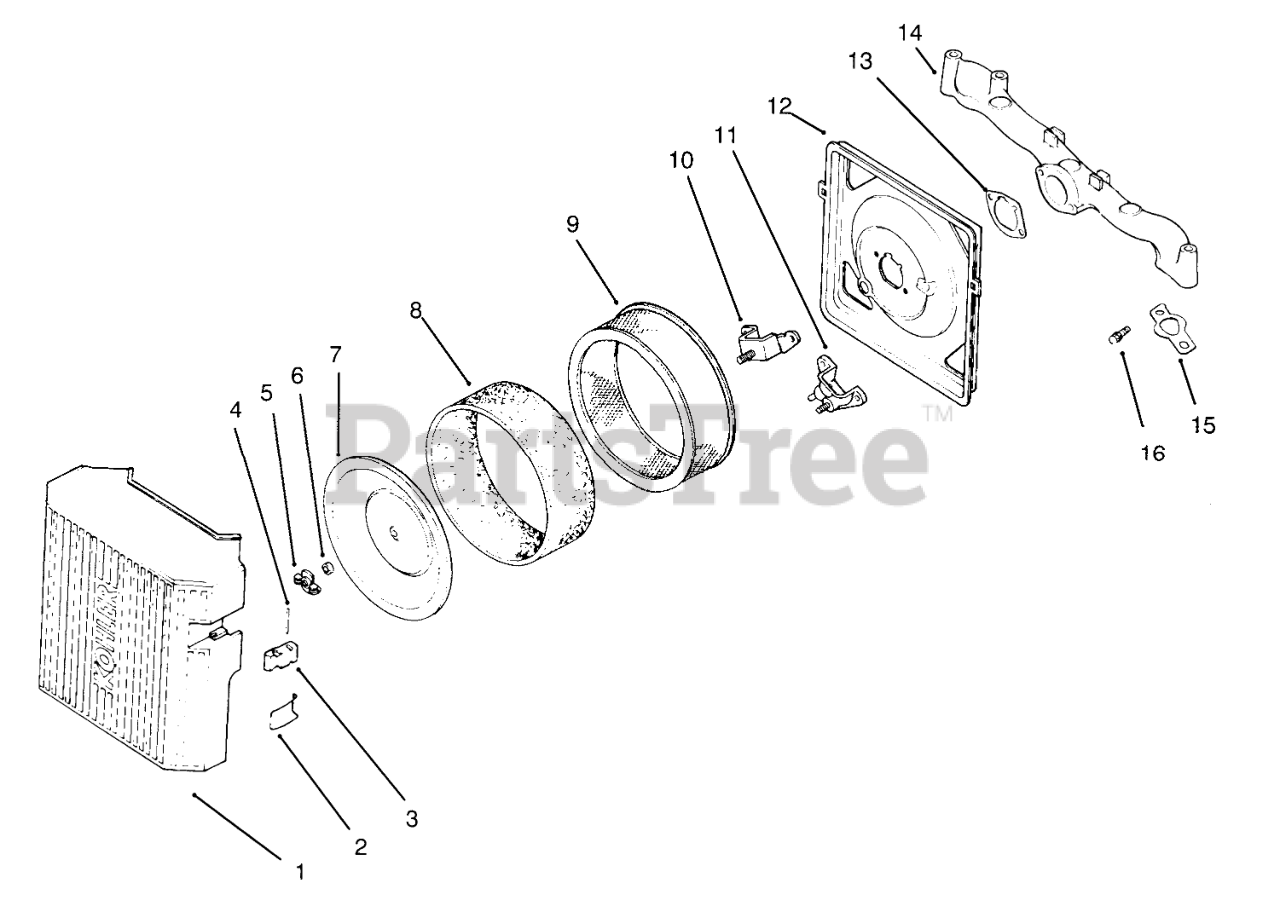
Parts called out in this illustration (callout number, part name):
1	Kit-A/C Cover INC 2-4
2	Spring-Latch
3	Latch-Lever
4	Pin-Latch Lever
5	Wingnut
6	Seal, insert
7	Cover-Inner AirCleaner
8	Bement-Precleaner
9	Bement-Air Cleaner
10	Cup-Fuel Spitback
11	Gasket-Fuel Spitback
12	Base-Air Cleaner
13	Gasket-A/C Base
14	Manifold-Intake
15	Gasket-Intake, Manifold
16	Screw
